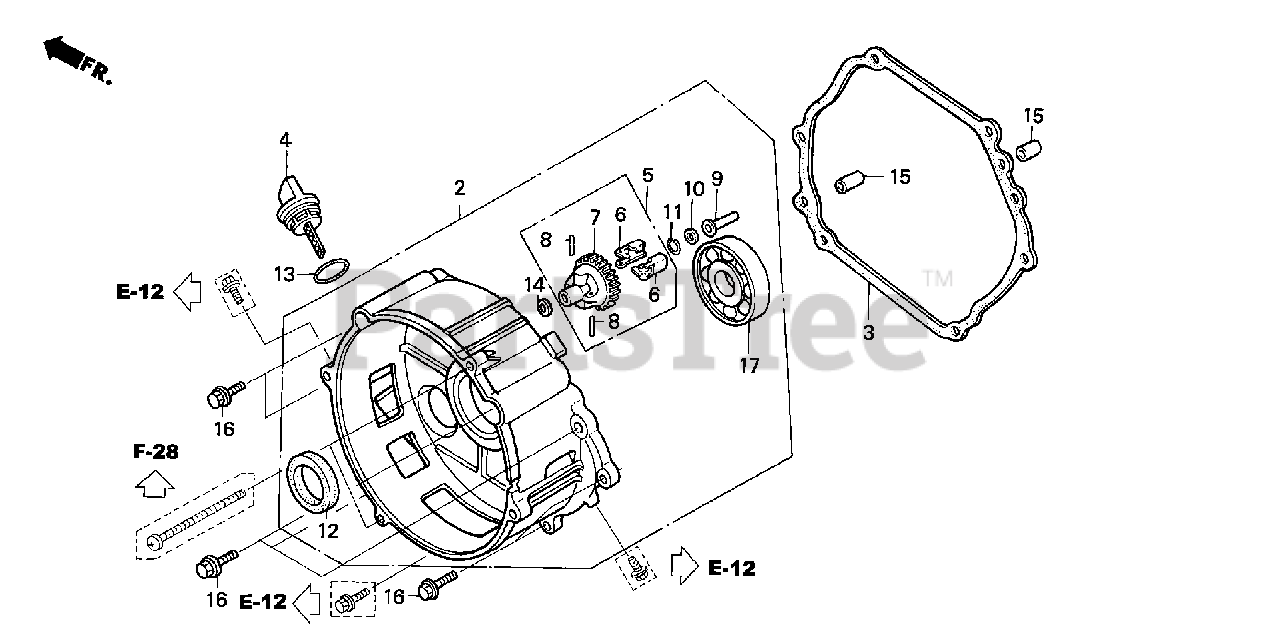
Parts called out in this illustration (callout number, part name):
2	COVER ASSY., CRANKCASE
3	GASKET, CASE COVER
4	CAP, OIL FILLER
5	GOVERNOR ASSY.
6	WEIGHT, GOVERNOR
7	HOLDER, GOVERNOR WEIGHT
8	PIN, GOVERNOR WEIGHT
9	SLIDER, GOVERNOR
10	WASHER (6X16)
11	CLIP, GOVERNOR HOLDER
12	OIL SEAL (30X46X8)
13	O-RING (26X2.7)
14	WASHER, PLAIN (6MM)
15	PIN, DOWEL (8X12)
16	BOLT, FLANGE (8X35)
17	BEARING, RADIAL BALL (6206)
